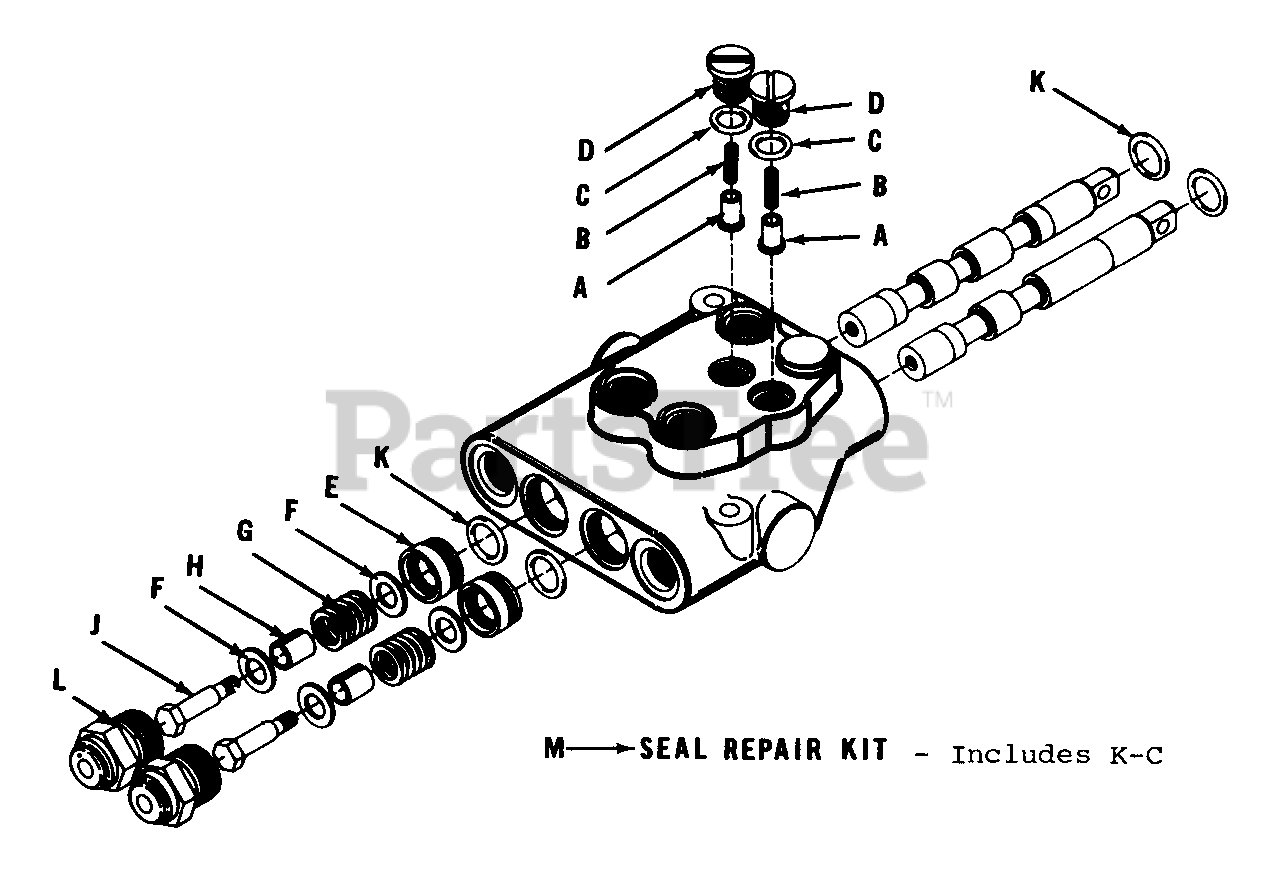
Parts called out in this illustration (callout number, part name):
A	Lift Check Plunger
B	Lift Check Spring
D	Lift Check Plug Ass'y.
F	Steel Washer
G	Spool Spring
H	Spool Spacer
J	Spool Screw
L	Cap Ass'y.
M	Major Seal Repair Kit
